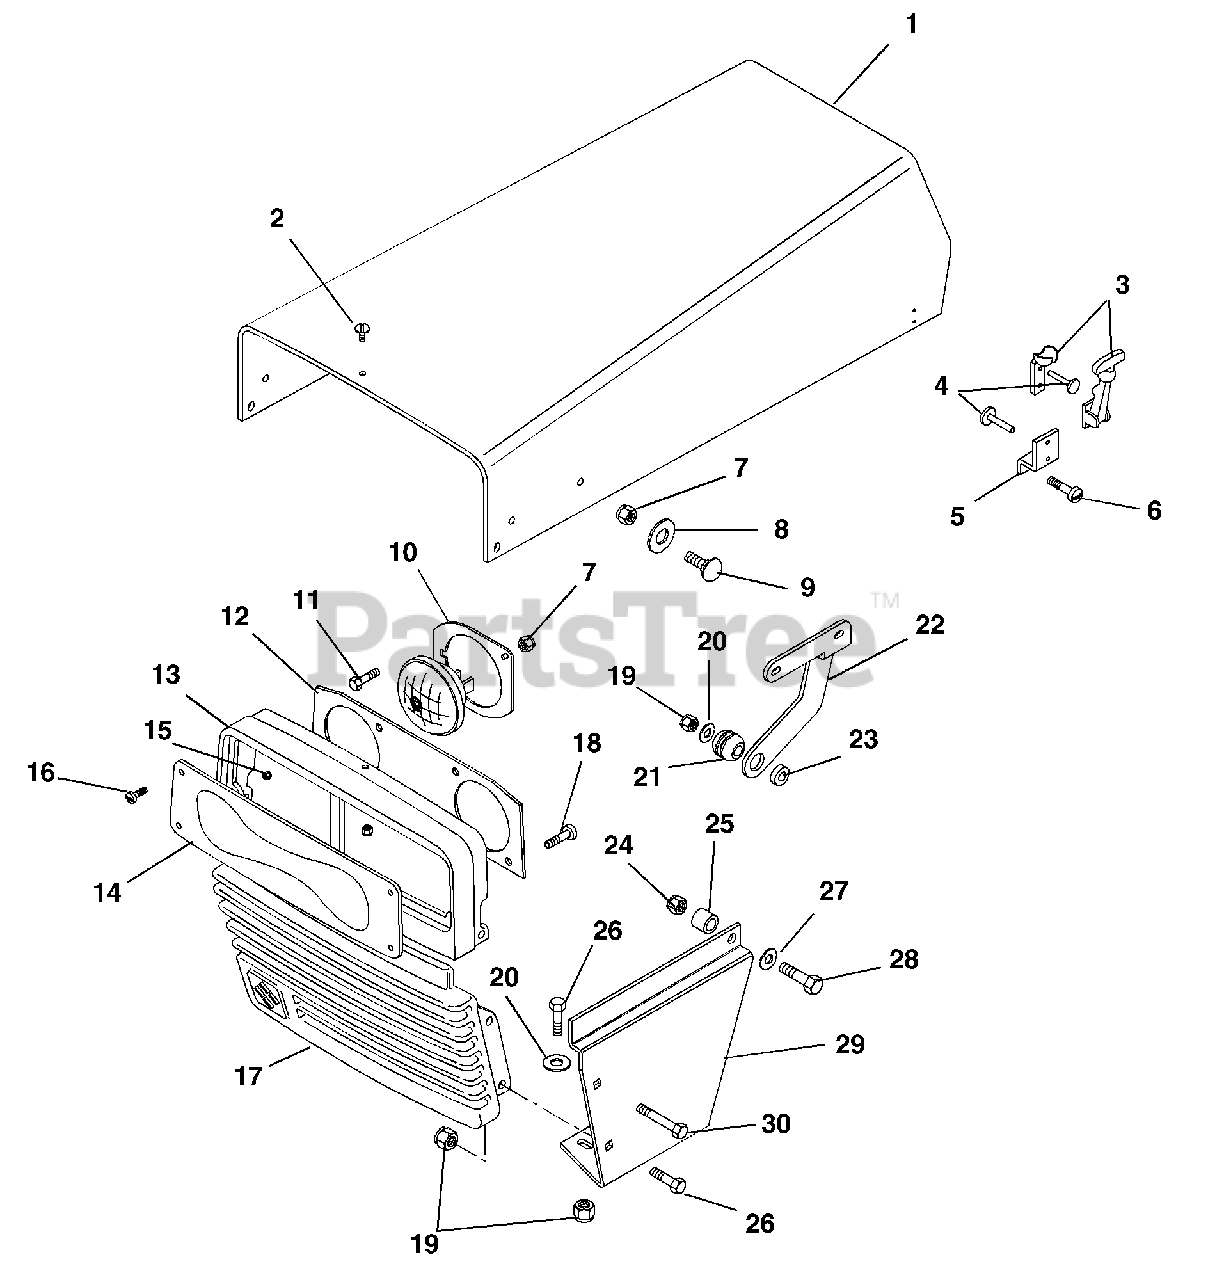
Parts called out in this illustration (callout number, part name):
1	Hood, Tractor
2	Screw-Machine .25-20 x .75
3	Latch, Flexible
4	Rivet-Pop .125 x .23
5	Bracket, Hood Latch Mounting
6	Screw-Tapping 8-32 x .50 Hex Washer Head
7	Nut-Locking-Center .25-20
8	Washer-Flat-Steel .28 x .62 x .065
9	Bolt-Round Head Square Neck .25-20 x .75 Grade 5
10	Ring, Head Light Retainer
11	Bolt-Hex .25-20 x 1.00 Grade 5
12	Panel, Headlight Reflector
13	Bezel, Headlight
14	Panel, Headlight Lense
15	Nut-Locking-Nylon 10-24 with Insert
16	Screw-Machine 10-24 x .75 Hex Washer Head
17	Grill
18	Screw-Tapping .25-20 x .50 Hex Washer Head
19	Nut-Locking-Center .38-16
20	Washer-Flat-Steel .44 x 1.00 x .083
21	Grommet
22	Hinge, Hood-Left Hand
22	Hinge, Hood-Right Hand
23	Spacer- Flanged .39 x .50 x .78 x .88
24	Nut-Locking-Center .31-18
25	Bushing-Sleeve Steel .41 x 1.00 x 1.00
26	Bolt-Hex .38-16 x 1.00 Grade 5
27	Washer-Flat-Steel .344 X .688 X .065
28	Bolt-Hex .31-18 x 1.75 Grade 5
29	Panel, Side Left Hand
29	Panel, Side Right Hand
30	Bolt-Hex .38-16 x 2.00 Grade 5
